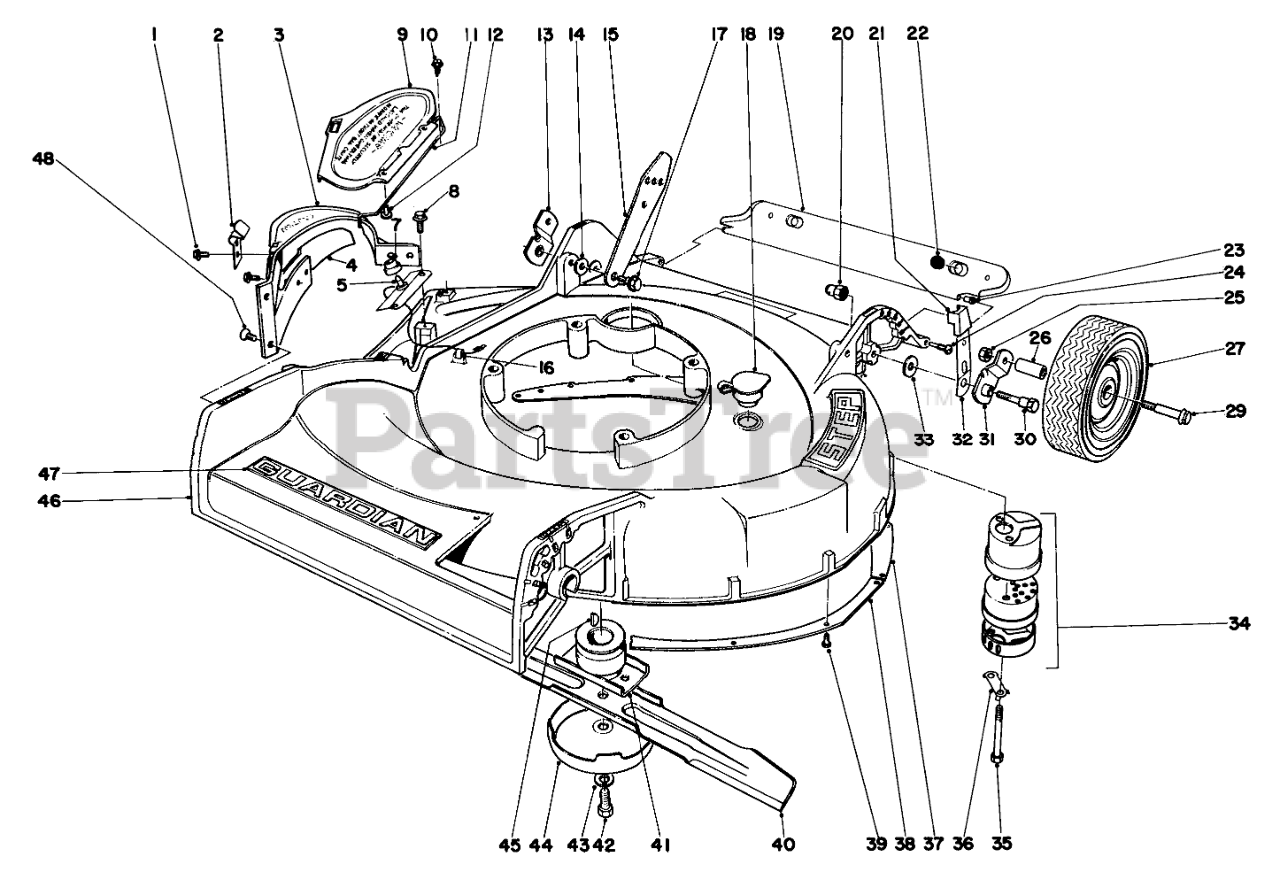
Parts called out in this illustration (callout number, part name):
2	Latch
3	Deflector (Incl. Ref. Nos. 1-4)
4	DefIector Bar
5	Switch & Wire (Incl. Ref. No. 7)
7	Boot Switch
9	Deflector Cover (Incl. Ref. Nos. 11 & 12)
10	SCREW
11	Hinge Pin
12	Rivet
13	Pivot Arm
14	SPACER
15	Handle Latch
17	SCREW-SHOULDER
18	WASHOUT PLUG
19	Safety Shield (Incl. Ref. Nos. 22 & 23)
20	HANDLE PIVOT NUT
21	Knob
22	SKID BUTTON
23	SAFTEY SHIELD BUSHING
24	SAFTEY SHIELD SCREW
25	Nut
26	Bushing
27	Wheel Assembly
30	5/16-18 PIVOT SCREW
31	Pivot Arm
32	Spring Arm
33	WASHER-PIVOT
34	Muffler (Incl. Ref. Nos. 35 & 36)
35	SCREW-HH
36	CLIP - LOCKING
37	Main Skirt
38	Secondary Skirt
40	Blade
41	BLADE RETAINER WA
42	SPECIAL SCREW
43	WASHER-LOCK
44	AntiScalp Cup
45	KEY-WOODRUFF
46	Housing (Incl. Ref. Nos. 37, 38 & 39)
47	Emblem
48	Screw
